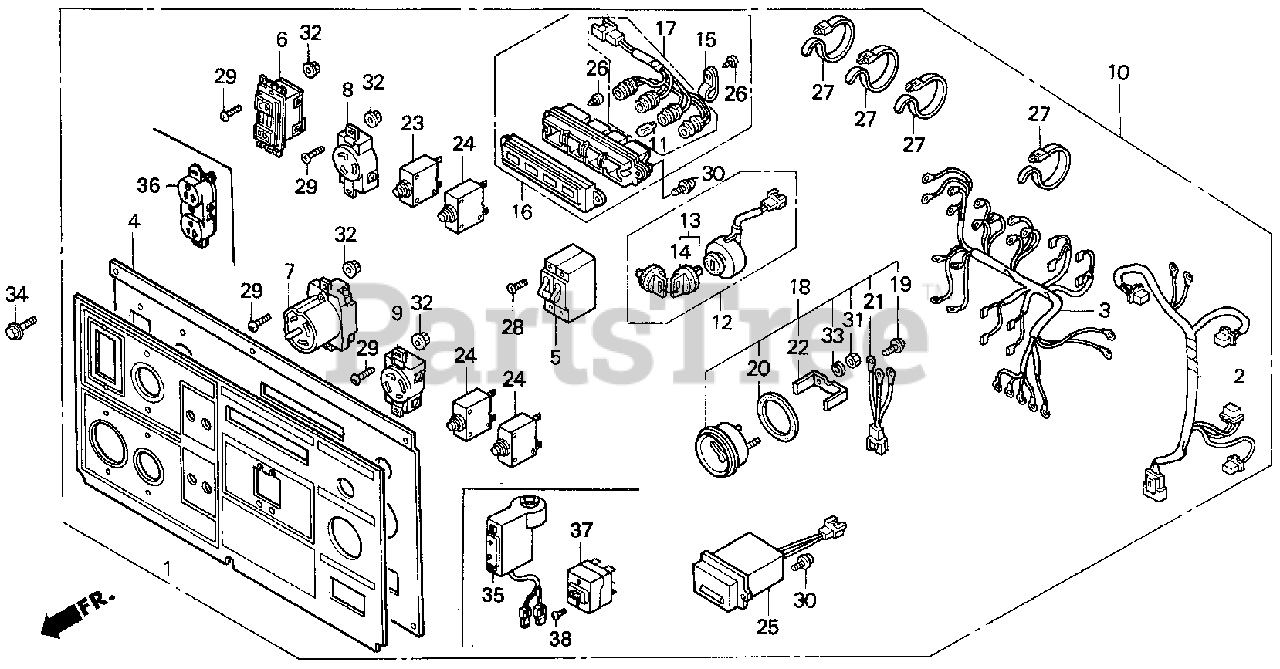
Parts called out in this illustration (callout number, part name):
1	PLATE, CONTROL INDICATION (AG)
2	WIRE HARNESS ASSY., CONTROL (MAIN)
3	HARNESS ASSY., CONTROL
4	PANEL, CONTROL *B132* (JOHN BLUE)
5	BREAKER, CIRCUIT (48A)
6	RECEPTACLE (20A-125V)
7	RECEPTACLE (50A-125/250V)
8	RECEPTACLE (3-PRONG) (30A/125V)
9	RECEPTACLE (30A-125/250V)
10	PANEL ASSY., CONTROL *B132* (JOHN BLUE)
11	BULB, WEDGE BASE (12V1.7W) (NIPPON SEIKI)
12	SWITCH ASSY., COMBINATION
13	KEY ASSY., COMBINATION SWITCH
14	CAP, COMBINATION SWITCH KEY
16	INDICATOR ASSY.
18	METER ASSY., FUEL
19	SCREW-WASHER (3X22)
21	WIRE ASSY.
23	PROTECTOR, CIRCUIT (20A)
24	PROTECTOR, CIRCUIT (30A)
25	METER ASSY., HOUR
26	SCREW, TAPPING (4X14)
27	TIE, CABLE
28	SCREW, PAN (3X6)
29	SCREW, PAN (4X12)
30	SCREW-WASHER (5X16)
31	NUT, HEX. (4MM)
32	NUT, FLANGE (4MM)
33	WASHER, SPRING (4MM)
34	BOLT, FLANGE (6X12)
